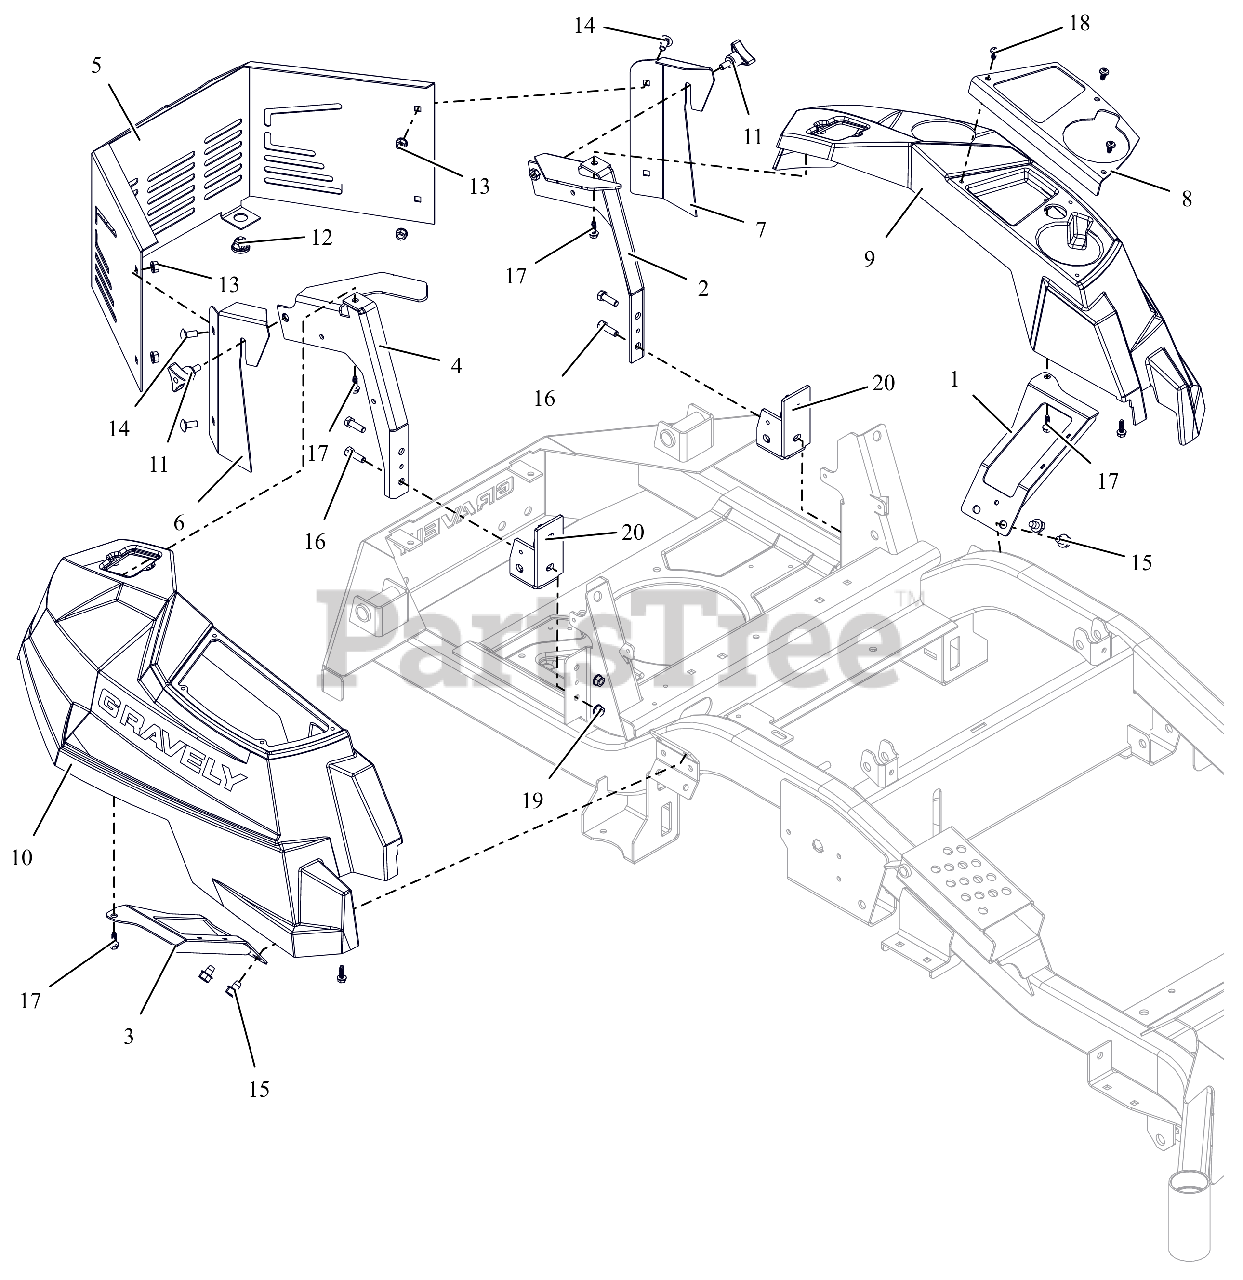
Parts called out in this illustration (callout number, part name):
1	WLDMT, LH FENDER MOUNT
2	BRKT, LH FENDER MTG
3	WLDMT, RH FENDER MOUNT
4	BRKT, RH FENDER MTG
5	GUARD, HD ENGINE
6	TRIM, HOOD STYLE (RIGHT)
7	TRIM, HOOD STYLE (LEFT)
8	PANEL, HD
9	KIT, FENDER W/FUEL DECAL-HD
10	FENDER, RH HD (2017) SHRT BOSS
11	KNOB,WING STUD 5/16-18 X .75
12	GROMMET, 10MM BOLLHOFF
13	NUT-LK-TOP-FLG .312-18 GF ZCC
14	BLT, RHSSN.31-18X.750 G5 ZCC
15	SCR,TAP .375-16X.50 HWH TR ZCC
16	BLT, HEX .31-18X1.00 G8 ZCC
17	SCR, PLASTITE-HWH 0.25 X 0.75 ZC120
18	SCR-PAN .25-15X.50 6L H/LZB500
19	NUT,LK-CTR-FLG .31-18 GF ZCC
20	BRKT, ROPS SUPPORT
